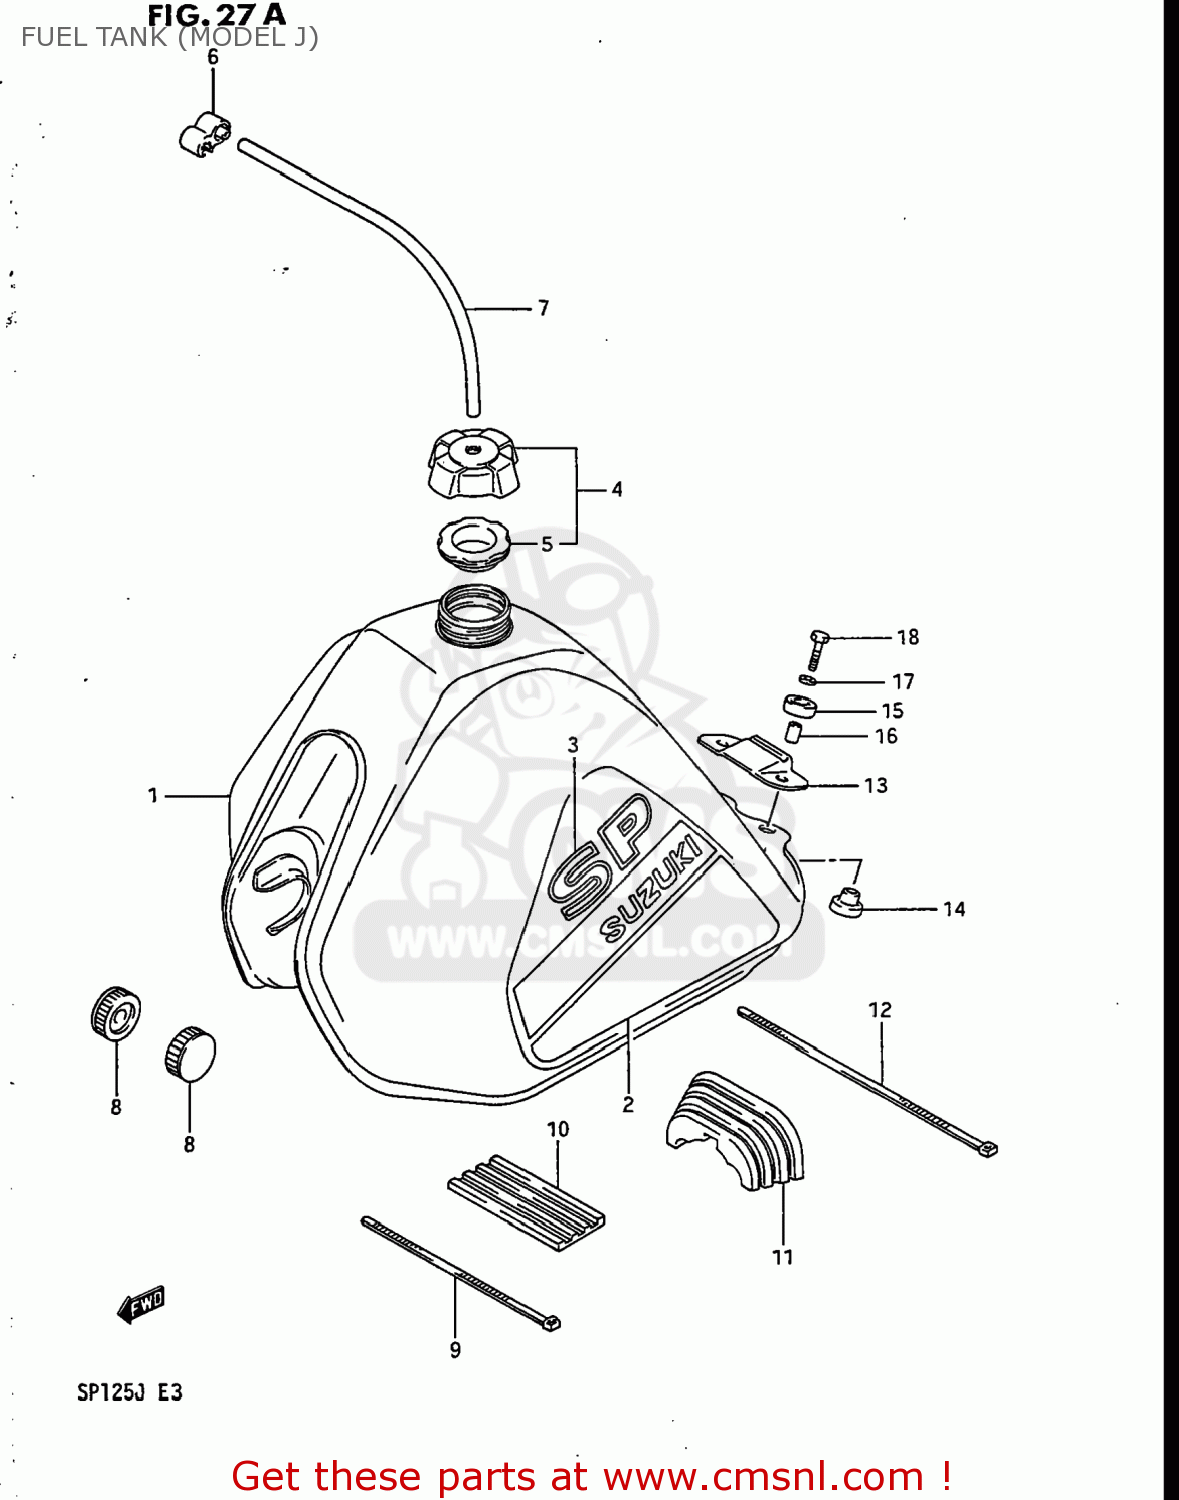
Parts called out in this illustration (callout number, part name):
1	TANK ASSEMBLY,FUEL (RED)
2	TAPE SET,FUEL TANK
3	EMBLEM,FUEL TANK
4	CAP SET,FUEL TANK
5	GASKET (NAS)
6	CLAMP,FUEL TANK BREATHER HOSE
7	HOSE
8	CUSHION
9	CLAMP
10	CUSHION,FUEL TANK UPR FR
11	CUSHION,FUEL TANK RR
12	CLAMP(L:250)
13	PLATE,SEAT FR HOOK
14	CUSHION
15	CUSHION
16	SPACER
17	WASHER,LOCK
18	BOLT
